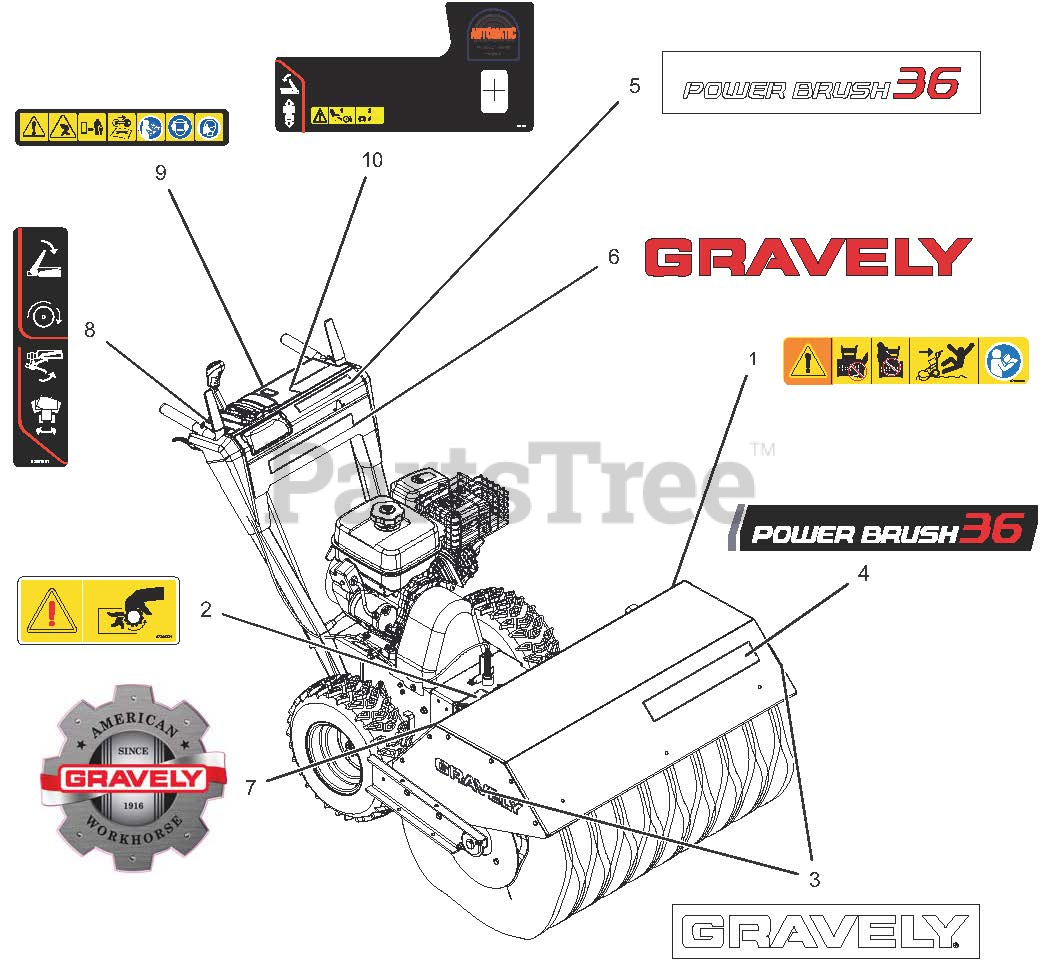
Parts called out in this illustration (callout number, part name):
1	DECAL, DANGER -POWER BRUSH-CE
2	DECAL, PTO WARNING
3	DECAL, 13.5" GRAVELY LOGO
4	DECAL,POWER BRUSH 36,GRAVELY
5	DECAL,POWER BRUSH 36,GRAVELY
6	DECAL,GRAVELY,RED,13"
7	DECAL, GRAVELY HERITAGE-LARGE
8	DECAL,CONTROL,BRUSH,RH
9	DECAL, SAFETY, DASH, BRUSH
10	DECAL,CNTRL,LRG BRUSH,LH,FRCTN
